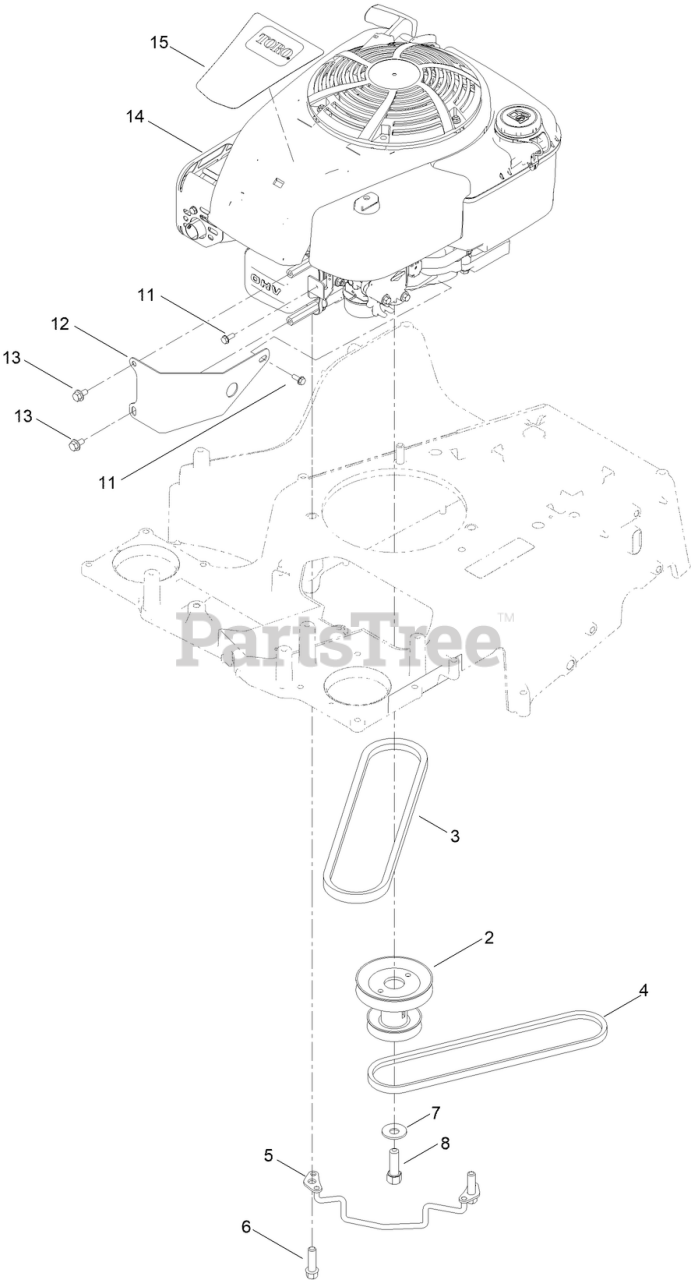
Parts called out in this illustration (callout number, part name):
2	PULLEY-ENGINE
3	V-BELT
4	V-BELT, TRACTION
5	GUIDE-BELT, WA
6	SCREW-TAPTITE
7	WASHER-BELLEVILLE
8	SCREW-HH
11	SCREW-TAPTITE
12	GUARD-ENGINE
13	SCREW-HHF
15	DECAL-SHROUD
